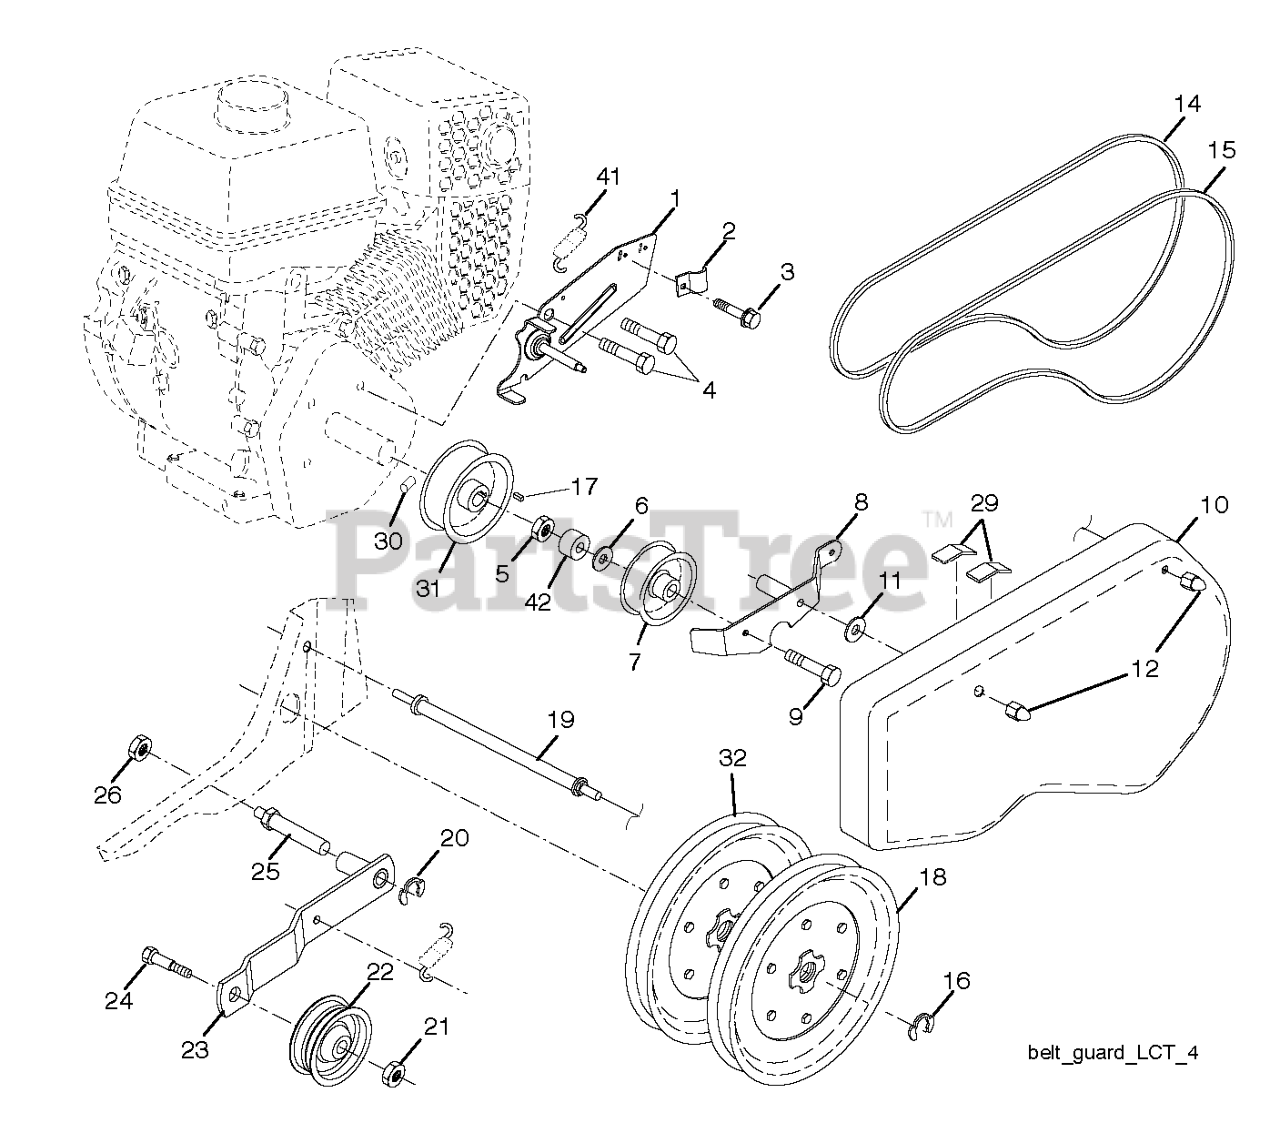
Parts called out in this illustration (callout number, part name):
1	BRACKET,BELTGUARD ASM
2	CLIP.PLATED
3	SCREW.HXTAP.10-24
5	NUT.LOCK.5/16-18
6	BUSHING SPACER.AXLE
7	PULLEY FLAT IDLER
8	ARM.ASM.REV.IDLER.TILLER.BLACK
9	BOLT.FIN HEX 5/16-18UNC X2 1/4
10	GUARD.BELT.TILLER.ORANGE
12	CAP
15	BELT.TILLER.DRIVE
16	RETAINING RING LT
17	KEY.SQ.187 X 1.125
18	SHEAVE,TRANS."D"
19	BOLT.BELT.GUARD
20	KLIP RING TI
21	NUT
22	PULLEY, IDLER
23	ARM.ASM.IDLER.
24	BOLT, HEX HEAD 3/8-16 X 1.25
25	SHAFT.IDLER.TILLER
26	JAM NUT TI
29	PAD IDLER TI
31	ENGINE.PULLEY.TILLER
32	SHEAVE.TRANS
41	SPRING.EXTENSION
42	SPACER.CONTROL.LEVER
